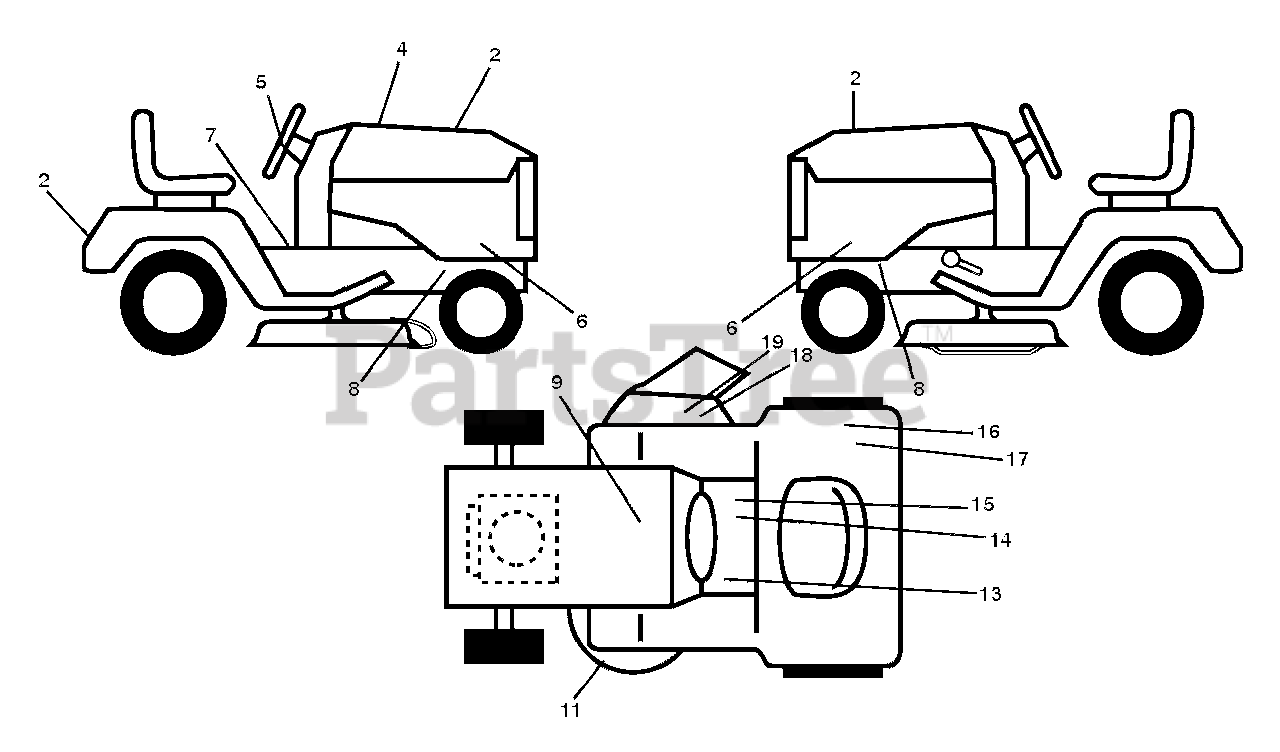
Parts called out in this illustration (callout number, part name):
1	DECAL.WARN.STARTINST.
2	DECAL, DIXON LOGO, DOMED
5	DECAL.WHEEL.STEER.DIXON
7	DECAL.FEND.SD.GT.SERIES.DIXON
8	DECAL.MOWER.SCH.48/54
9	DECAL BTRY SYMBOLS
11	DECAL.MOWER
